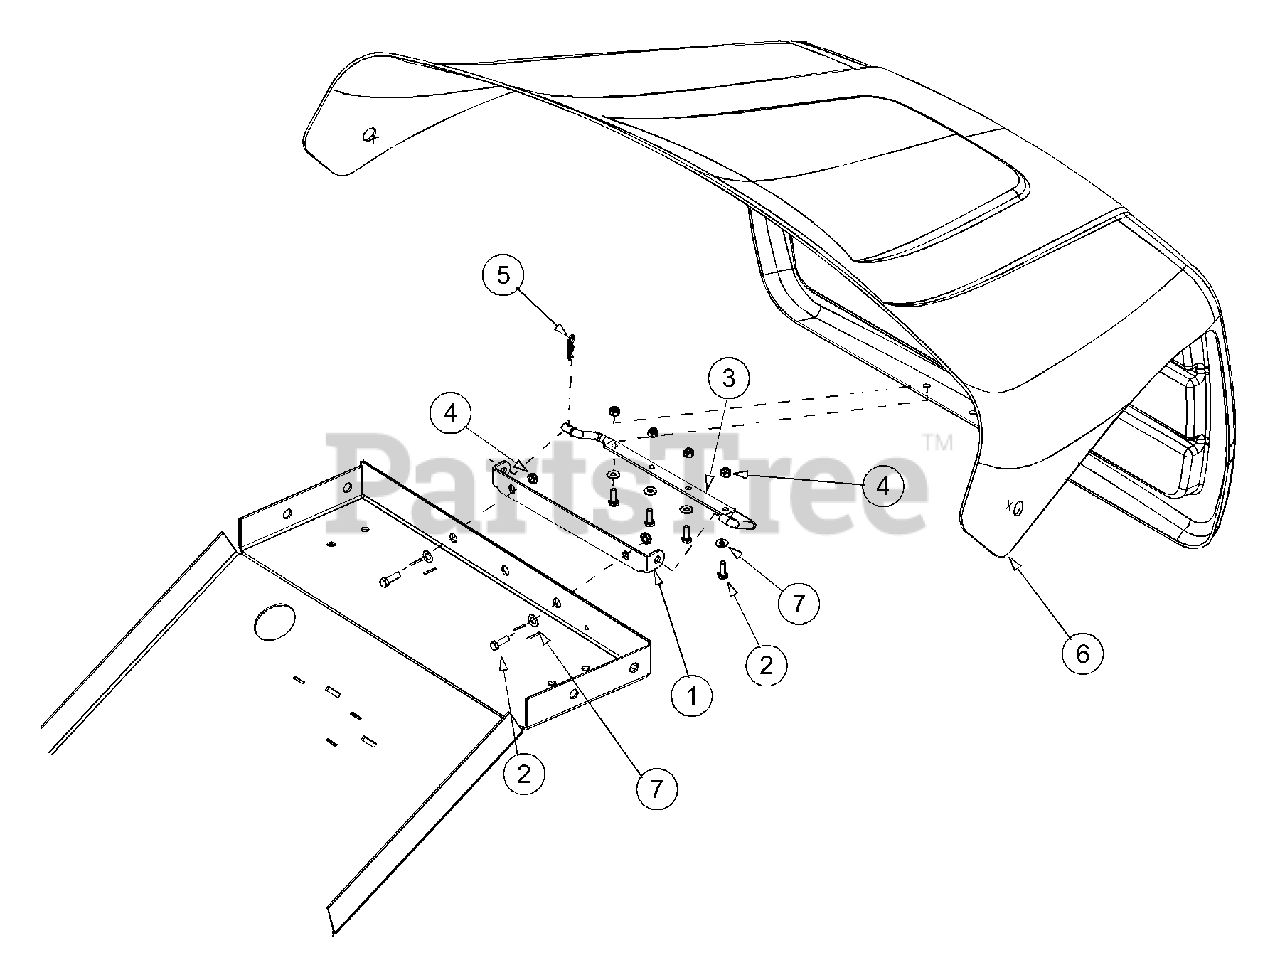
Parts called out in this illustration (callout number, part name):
3	Rod Mounting Hood
4	Nut, Nylon Hex Lock, 1/4-20, Gr8
5	Cotter Pin
6	Panel, Hood
7	Washer, Flat, .271 x .630 x .065
